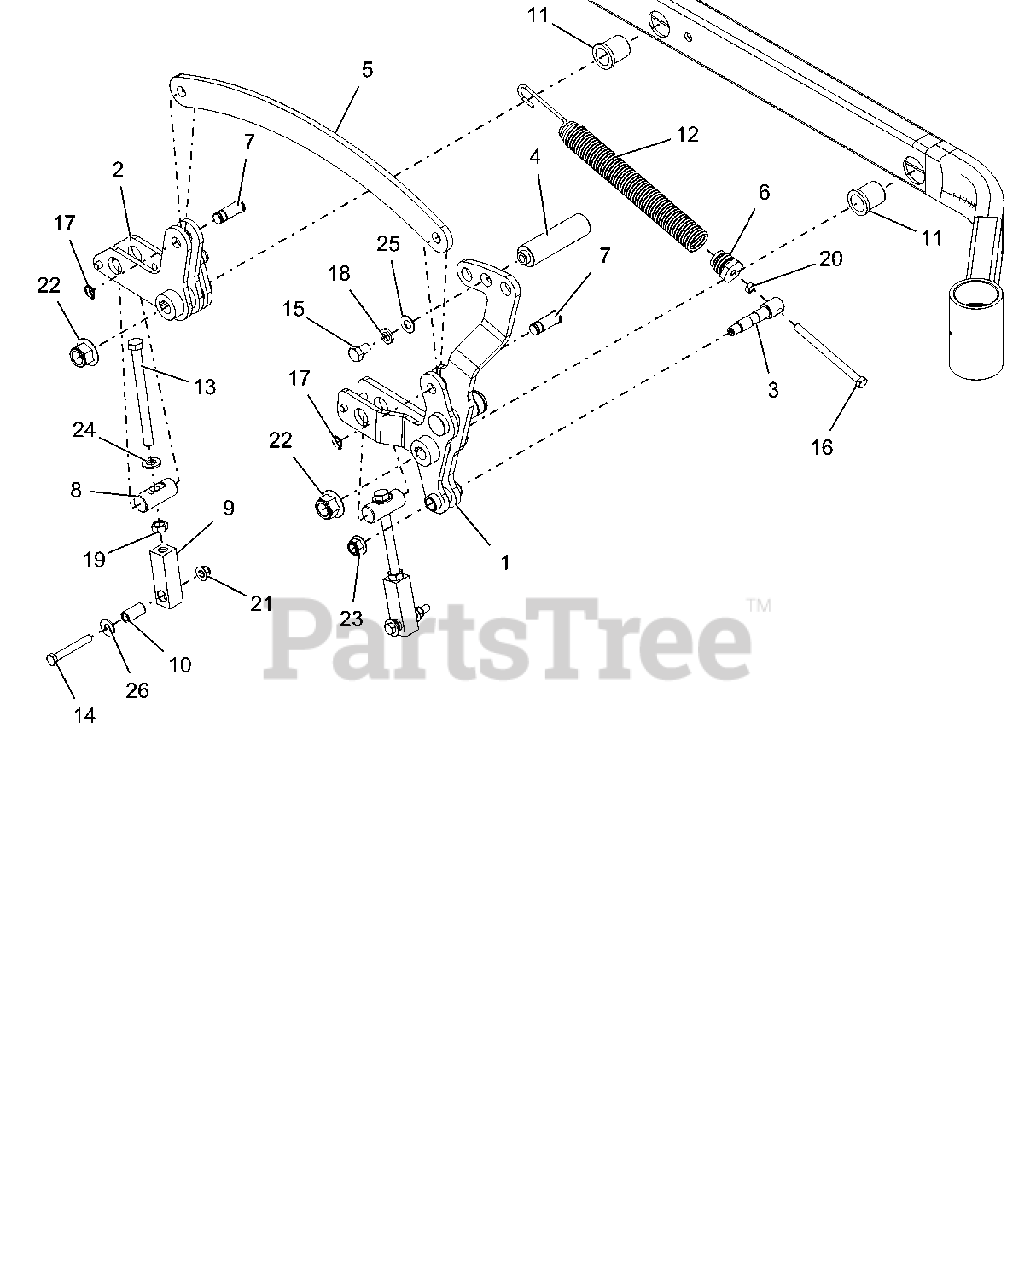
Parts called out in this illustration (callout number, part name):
1	FRONT RH DECK LIFT ARM WMT-LF
2	REAR RH DECK LIFT ARM WLDMT-LF
3	TRUNION, DECK LIFT SPRING
4	FOOT PEG, DECK LIFT
5	LINK, CONNECTING
6	PLUG, SPRING
7	PIN, CLEVIS .625 SNAP RING
8	PIN, DECK LIFT
9	LINK, DECK LIFT
10	SPACER, DECK LEVELING
11	BSHG-FLG 1.00X1.25X1.50X1.50
12	SPRING, DECK LIFT
13	BOLT,.50-13X6.00-2.50 LG THD
14	BLT-HEX .38-16X2.75 GR8 YWZC
15	@BLT-HEX .50-13X.75 GR5 YWZC
16	BLT-HEX .38-16X5.00 GR5 FTH YZ
17	RG-RTNG-EXT .625X.050
18	@WSHR-LK .50X.125 REG YWZC
19	NUT-JAM .50-13 YWZC
20	NUT-HEX-JAM .375-16 YWZC
21	@NUT-LK-NYL-FLG .38-16 YWZC
22	@NUT-LK-NYL-FLG .75-10 YWZC
23	@NUT-LK-NYL-FLG .50-13 YWZC
24	FLATWASHER 1/2 SAE HARD 15906
25	WSHR-FL-STL .505X1.00X.062YWZC
26	@WSHR-FL-STL.438X1.00X.083 YWZ
